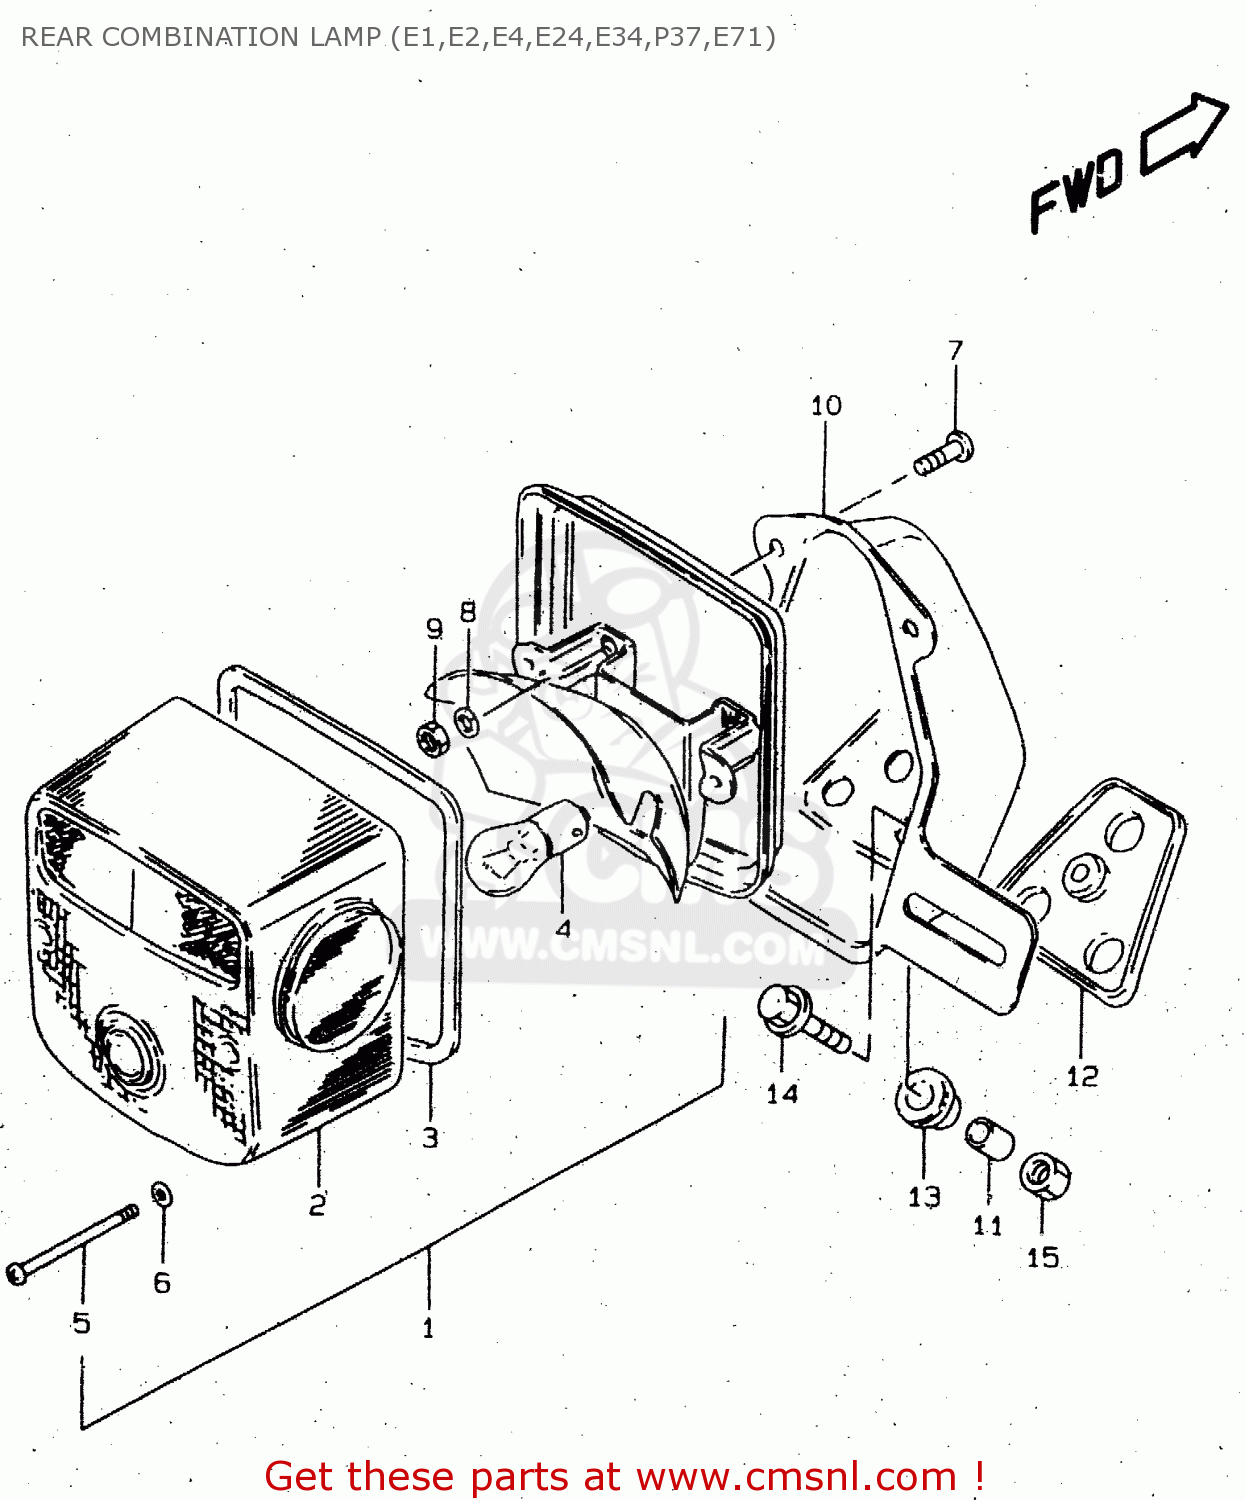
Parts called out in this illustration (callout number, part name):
1	LAMP UNIT, TAIL
2	LENS
3	GASKET (NAS)
4	BULB(12V23W)
5	SCREW (4X55)
6	GASKET (NAS)
7	SCREW
8	WASHER,LOCK
9	NUT
10	BRACKET UNIT,TAIL LAMP
11	SPACER
12	CUSHION
13	CUSHION
14	BOLT(6X20)
15	NUT 6MM
